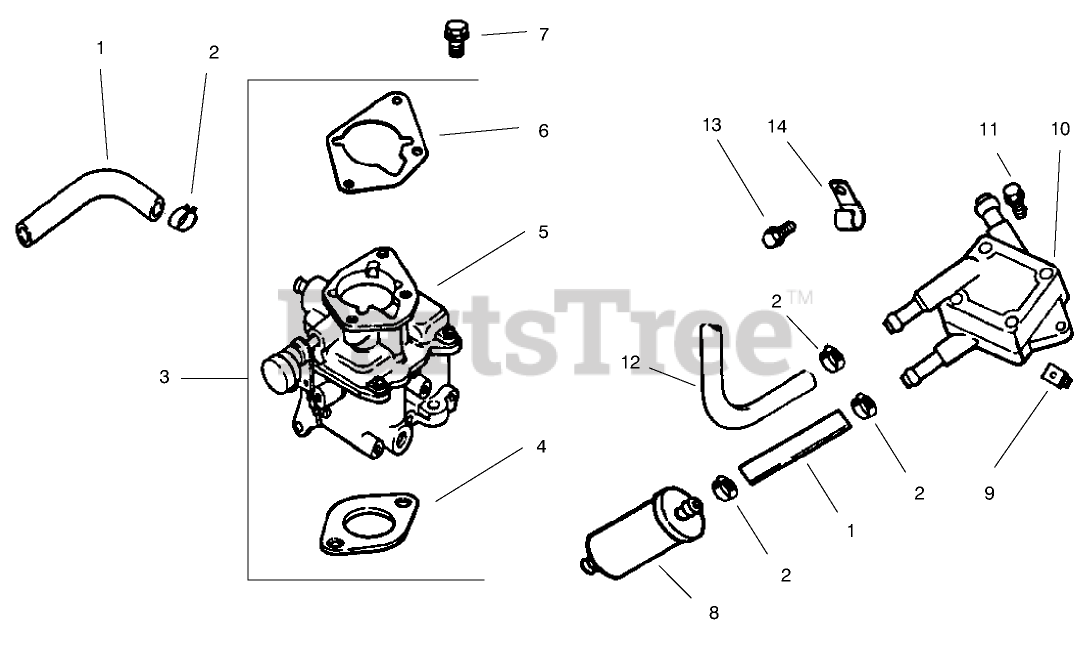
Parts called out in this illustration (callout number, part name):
1	Line fuel
2	Clamp
3	Kit, carburetor w/gasket (Includes 4-6)
4	Gasket
5	Carburetor assembly
6	Gasket
7	Screw
8	Filter-Fuel
9	Nut
10	Pump-Fuel
11	Screw
12	Line, fuel17"
13	Screw
14	Clamp
